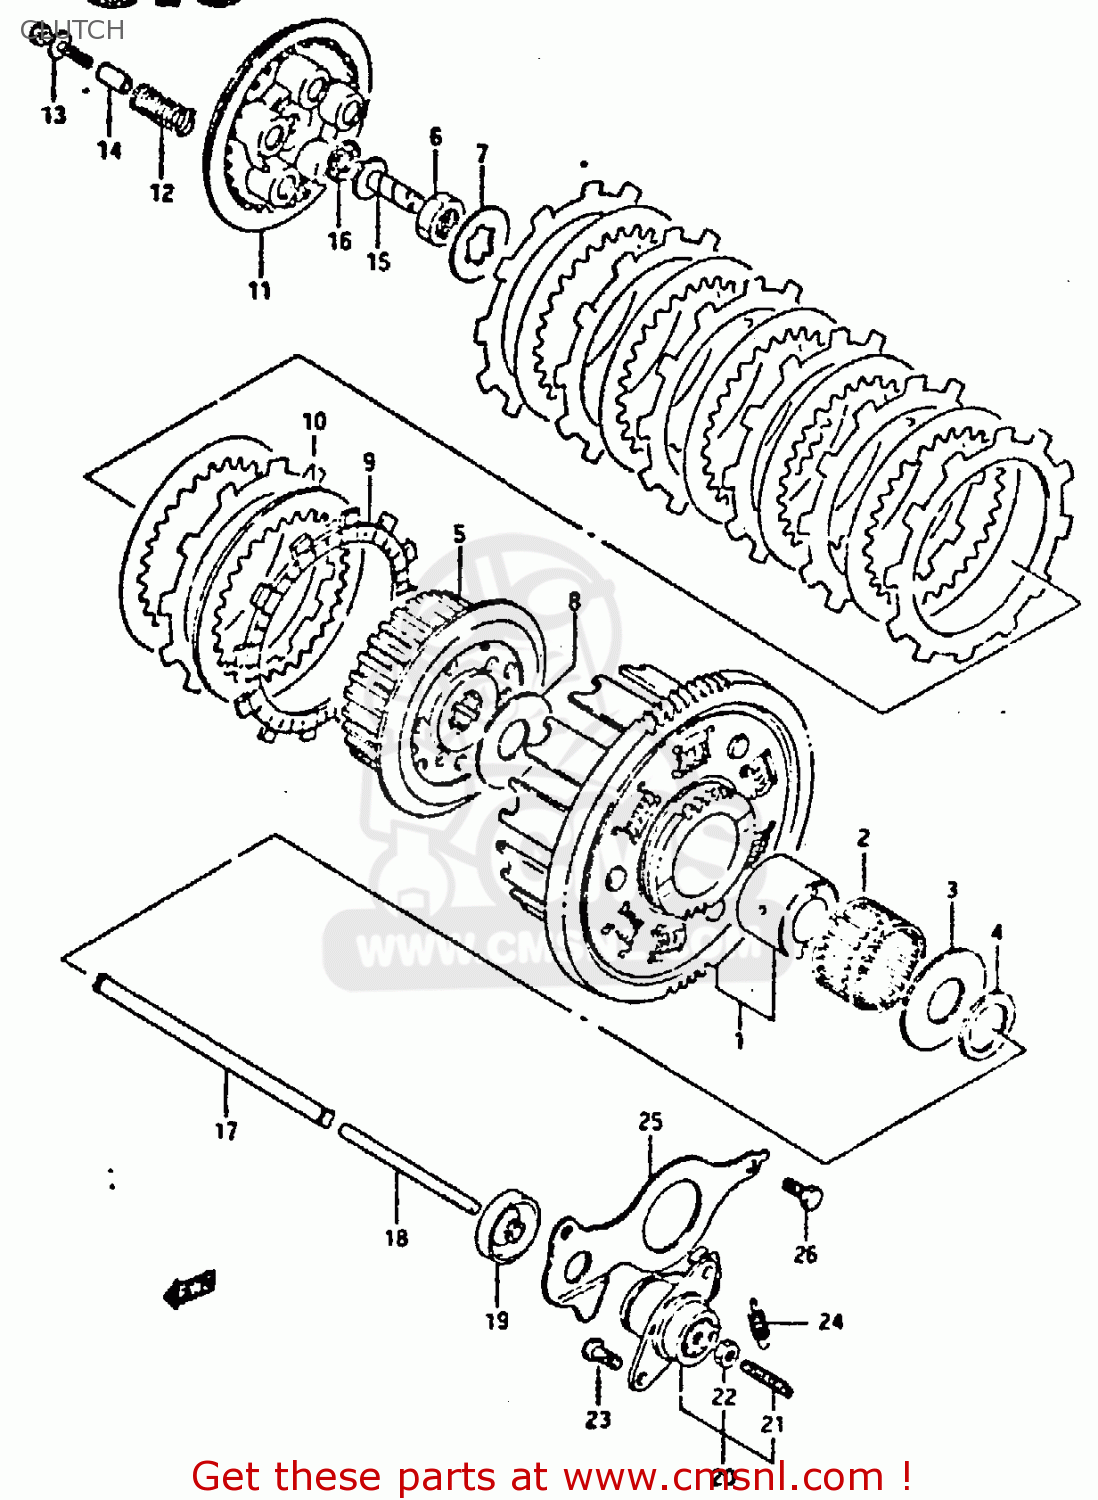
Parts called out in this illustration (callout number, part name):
1	PRIMARY DRIVEN
2	BEARING(37X42X27)
3	WASHER,22X50X2.5
4	WASHER(22X32X3)
5	HUB,CLUTCH SLEEVE
6	NUT
7	WASHER,LOCK
8	WASHER(20X50X2)
9	PLATE,CLUTCH DRIVE (NAS)
10	PLATE,CLUTCH DRIVEN (NAS)
11	DISC,CLUTCH PRESSURE
12	SPRING
13	BOLT(5X40)
15	ROD,CLUTCH RELEASE
16	BEARING(10X22X2.8)
17	ROD,CLUTCH PUSH
18	ROD,CLUTCH PUSH,L
19	SEAL,OIL(6X34X7.5)
20	SCREW ASSY,CLUTCH RELEASE
21	SCREW(6X25)
22	NUT 6MM
23	SCREW 6X12
24	SPRING
25	RETAINER,PUSH ROD OIL SEAL
26	BOLT
